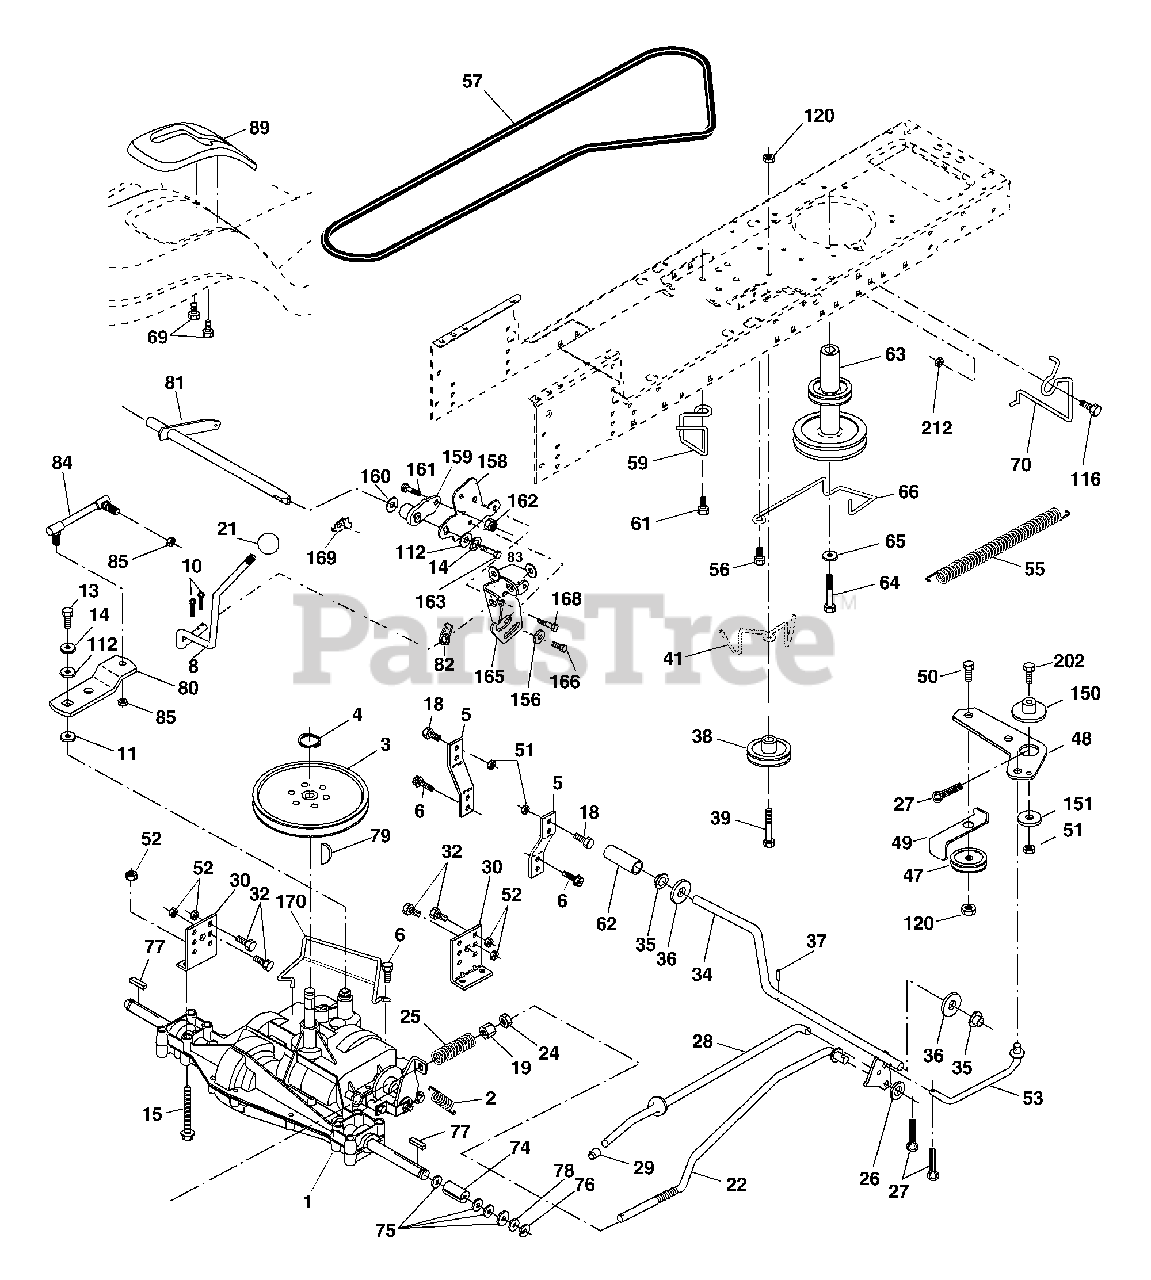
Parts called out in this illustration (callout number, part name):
2	Spring, Return, Brake
3	Pulley, Transaxle
4	Ring, Retainer
5	Strap, Torque
6	Screw 5/16-18 x 3/4
8	Rod Shifter Fender STLT
10	Pin, Cotter
11	Washer, Shift Plate
13	Bolt 1/4-28 UNF W/Patch Gr. 8
14	Washer Lock Hvy Helical
15	Bolt Hex Flghd 5/16-18 Gr. 5
16	Nut Lock Hx W/Ins 5/16-18
18	Bolt Fin Hex 3/8-16 unc x 1 Gr. 5
19	Nut
21	Knob
22	Rod, Brake
24	Nut
25	Spring, Brake Rod
26	Washer
27	Pin
28	Rod, Parking Brake
29	Cap, Parking Brake
30	Bracket, Transaxle
32	Bolt
34	Shaft Assembly, Foot Pedal
35	Bearing, Nylon
36	Washer
37	Roll Pin
38	Pulley, Composite, Flat
39	Bolt Rdhd 3/8-16 unc x 2-3/4 Gr. 5
41	Keeper, Belt, Idler
47	Pulley, Idler, V-Groove, Plastic
48	Bellcrank Clutch Grnd Drv Stl
49	Retainer, Belt
50	Bolt Carr. Sh. 3/8-16 x 1-1/2 Gr. 5
51	Nut Crown Lock 3/8-16 unc
52	Nut Crown Lock 5/16-18 unc
53	Link, Clutch
55	Spring, Clutch Return
56	Screw 3/8-16 x 1-1/4
57	V-Belt, Ground Drive
59	Keeper, Belt, Center Span
61	Screw 3/8-16 x .875
62	Cover, Pedal
63	Pulley, Engine
64	Bolt, Hex 7/16-20 x 4 Gr. 5
65	Washer
66	Keeper, Belt, Engine, Fool-Proof
69	Screw, Hex, Wsh, Hi-Lo 1/4 x 1/2 unc
70	Guide, Mower Drive Belt, R.H.
74	Spacer, Axle
75	Washer 25/32 x 1-1/4 x 16 Ga.
76	E-Ring
77	Key, Square 2.0 x .1845/.1865
78	Washer 25/32 x 1-5/8 x 16 Ga.
79	Key Woodruff
80	Arm, Shift
81	Shaft Asm Cross
82	Spring, Torsion
83	Washer 17/32 x 3/4 x 16 Ga.
84	Link Transaxle
85	Nut, Nylock
89	Console, Shift, STLT
96	Retainer Spring 1"
112	Washer 9/32 x 3/4 x 10 Ga.
113	Strap Torque 90 Degrees
116	Bolt Rdhd Sqneck 3/8-16 x 1
120	Nut Lock Flg. 3/8-16
150	Spacer Retainer
151	Washer 13/32 x 2 x 10 Ga.
156	Washer Srrted 5/16 ID x 1.125
158	Bracket Shift Mount
159	Hub Shift
161	Bolt Rdhd Sqnk 1/4-20 x 3/4 Gr.5
162	Nut Crownlock 1/4-20 unc
163	Bolt Hex Fin 1/4-20 unc x 1 Gr. 5
165	Bracket Pivot Lever
166	Screw 5/16-18 x 5/8
168	Bolt Shoulder 5/16-18 x .561
169	Plate Fastening Lt
170	Keeper Belt Transaxle
197	Nyliner Snap-In
198	Washer Nyliner
202	Bolt Carr. SH 3/8-16 x 1-3/4 Gr. 5
212	Nut Hex Flg. Lock
